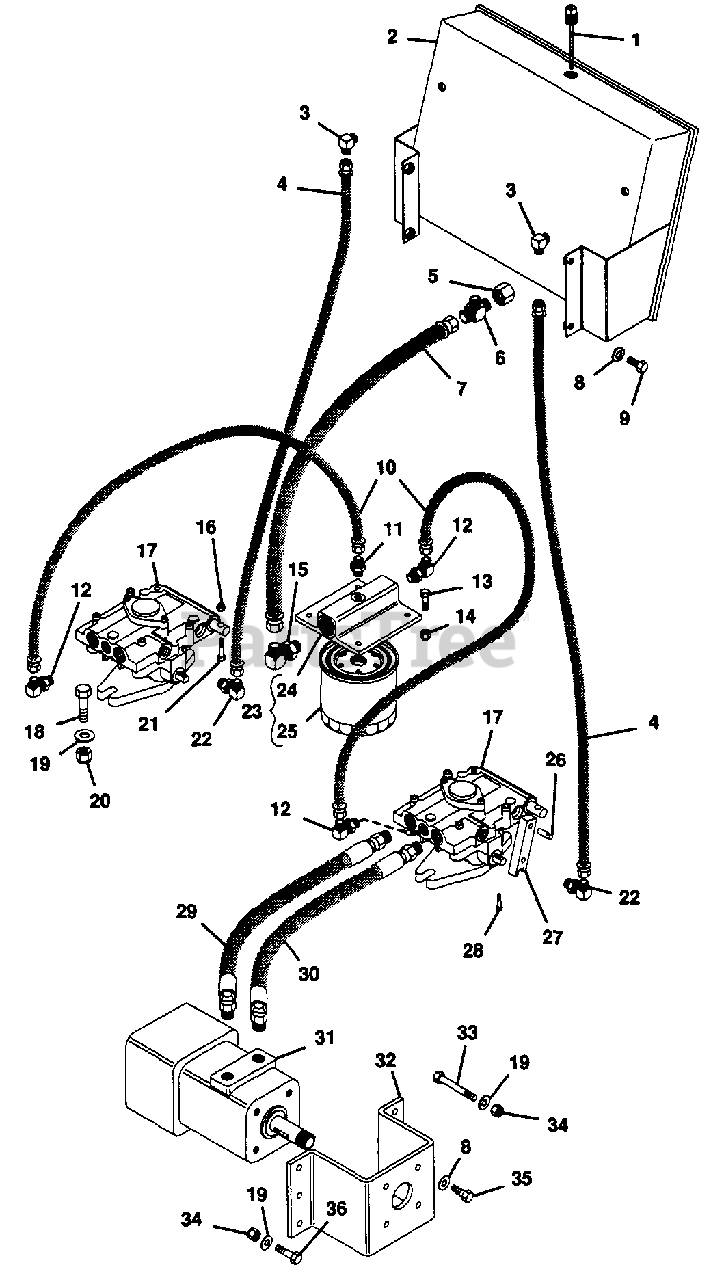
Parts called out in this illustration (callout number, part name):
1	Gauge, Hydraulic Tank Level
2	Tank, Hydraulic Oil
3	Adaptor, 2501-6-4 90 Deg. Elbow
4	Hose, Hyd. Valve to Tank
5	Capnut, 304-C-8
6	Adaptor, 2601-8-8-6 Side Tee
7	Hose, Tank to Filter
8	Washer, Lock 3/8 Reg.
9	Bolt, Hex 3/8-16x.75
10	Hose, Oil Filter to Pump
11	Adaptor, 0503-4-4
12	Adaptor, 2503-4-4
13	Bolt, Hex 5/16-18x1.00
14	Nut, Lock 5/16-18
15	Adaptor, P-H #2503-8-8
16	Nut, Lock 1/4-20
17	Pump, Variable Displace
18	Bolt, Hex 3/8-16x1.125
19	Washer, Flat .406x.812x.065
20	Nut, Lock 3/8-16
21	Bolt, Hex 1/4-20x1.25
22	Adaptor, 2503-6-6
23	Assembly, Spin-On Lube
24	Assembly, Head
25	Element
26	Pin, Dowel
27	Arm, Pump Actuating
28	Screw, Cap 10-24x.75 Hex Socket
29	Asm, Hose Wheel Motor to Pump
30	Asm, Hose Wheel Motor to Pump
31	Motor, Hydraulic Wheel
32	Bracket, Wheel Motor
33	Bolt, Hex 3/8-16x2.5
34	Nut, Lock 3/8-16
35	Bolt, Hex 3/8-16x.875
36	Bolt, Hex 3/8-16x1.00
